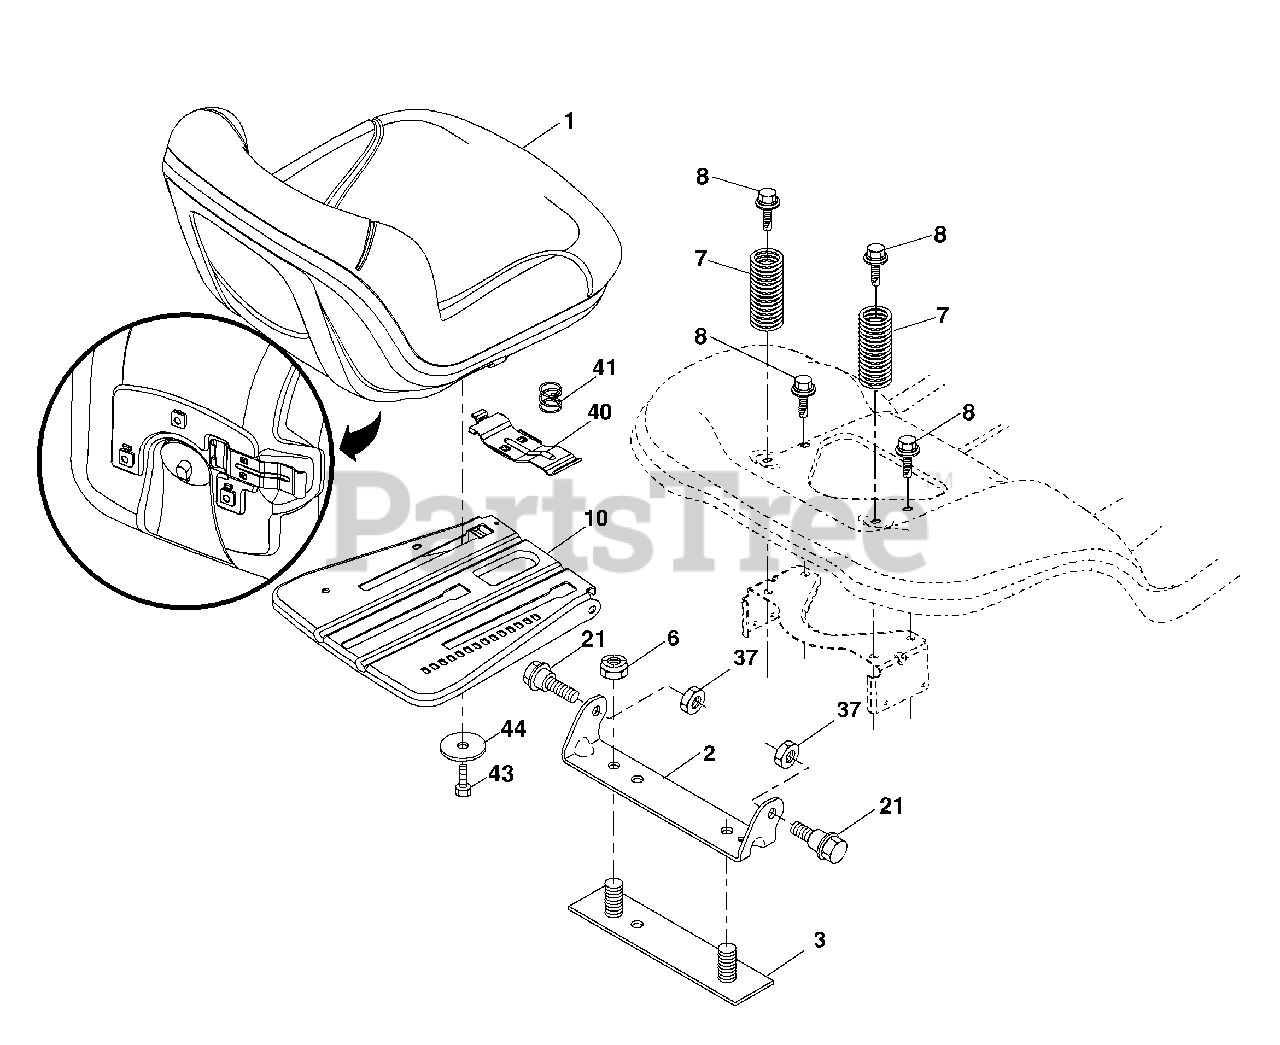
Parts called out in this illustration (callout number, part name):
1	Seat
2	Bracket Pivot Fender
3	Strap, Asm Fender
6	Nut, Lock w/Ins. 3/8-16 unc
7	Spring, Seat Cprsn
8	Bolt 5/16-18 unc x 3/4 w/Sems
10	Pan, Seat
21	Bolt, Shoulder 5/16-18
37	Nut, Lock 5/16-18 unc
40	Handle Slide Seat
41	Spring Latch Seat
43	Bolt Fin Hex 3/8-16 unc x 3/4
44	Washer 13/32 x 2-3/8 x 12 Ga.
